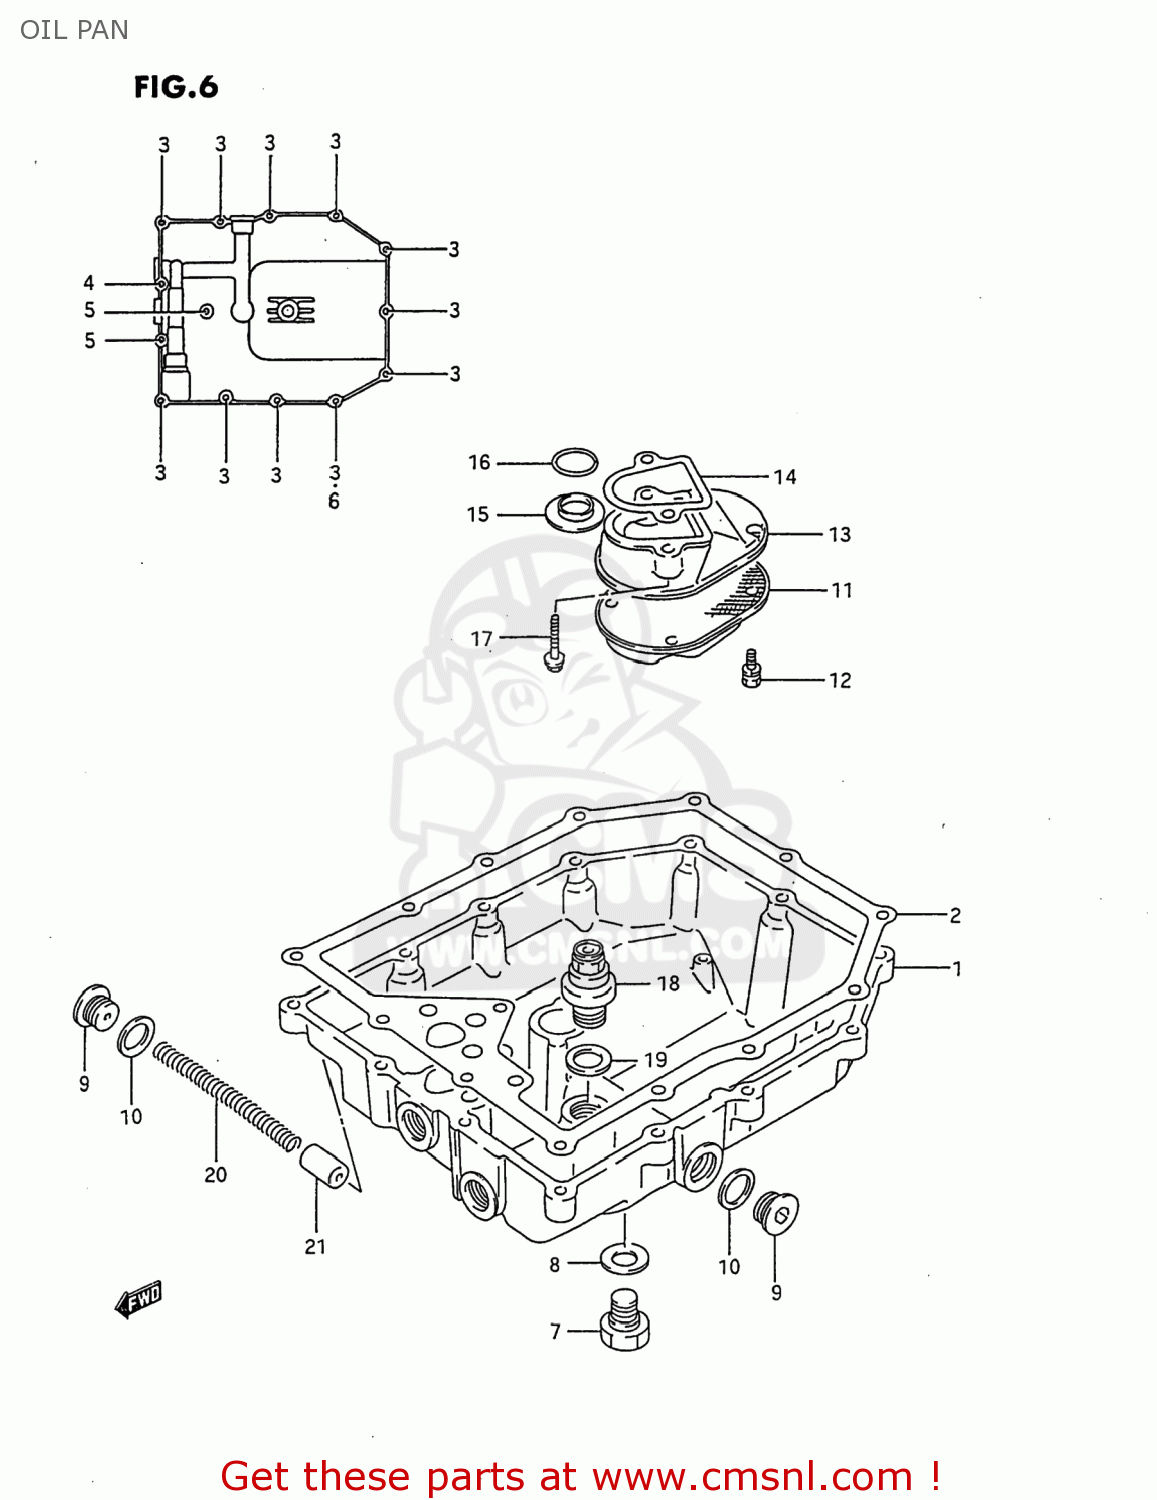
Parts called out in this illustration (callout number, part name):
1	PAN,OIL
2	GASKET,OIL PAN (NAS)
3	SCREW
4	BOLT
5	BOLT
6	GASKET(5.8X11X1.2) (NAS)
7	PLUG
8	GASKET(13.8X18.8X4.8) (NAS)
9	PLUG
10	GASKET(16X22X2) (NAS)
11	STRAINER,ENGINE OIL
12	BOLT
13	PROTECTOR,OIL STRAINER
14	GASKET,OIL STRAINER PROTECTOR (NAS)
15	GASKET,OIL OUTLET (NAS)
16	O RING(D:3.2,ID:17.8)
17	BOLT
18	VALVE ASSEMBLY,OIL RELIEF
19	GASKET(16X22X2) (NAS)
20	SPRING
21	PLUNGER,OIL CONTROLL
